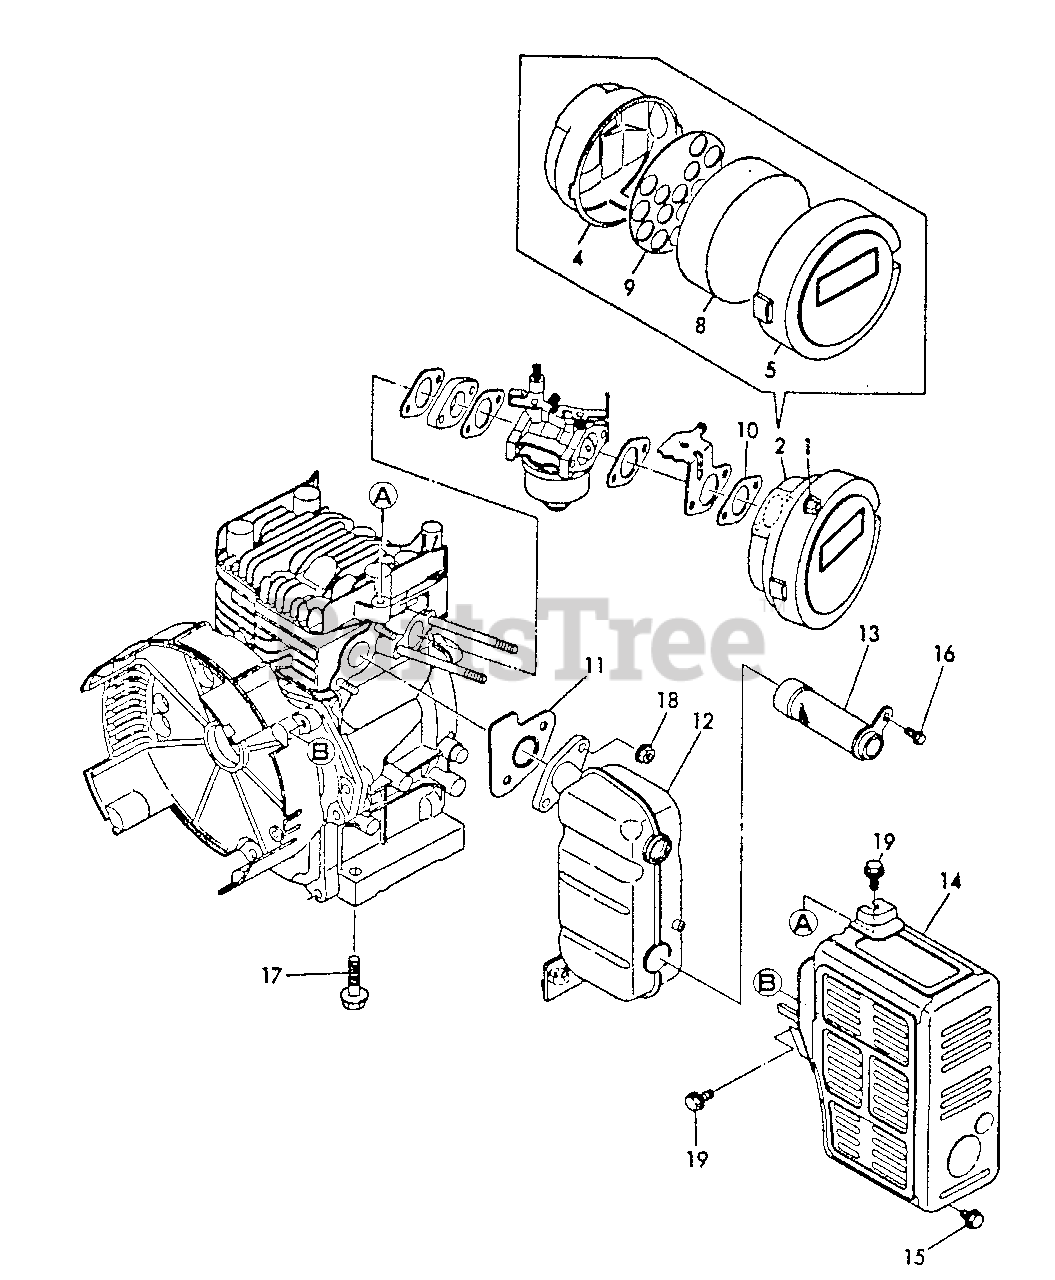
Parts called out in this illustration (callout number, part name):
1	NUT - 6 -- FLANGE
2	AIR CLEANER ASSY
4	CASE, AIR FILTER
5	COVER, AIR FILTER
8	FILTER, AIR
9	RETAINER, AIR FILTER
10	GASKET, INTAKE
11	GASKET, EXHAUST
12	MUFFLER
13	SCREEN, SPARK ARRESTOR
14	COVER, MUFFLER
15	BOLT - 6X8 -- PLATED
16	BOLT - 6X10 -- PLATED
17	BOLT - 8X30 -- PLATED
18	NUT - 6 -- FLANGE
19	BOLT - 6X8 -- PLATED
